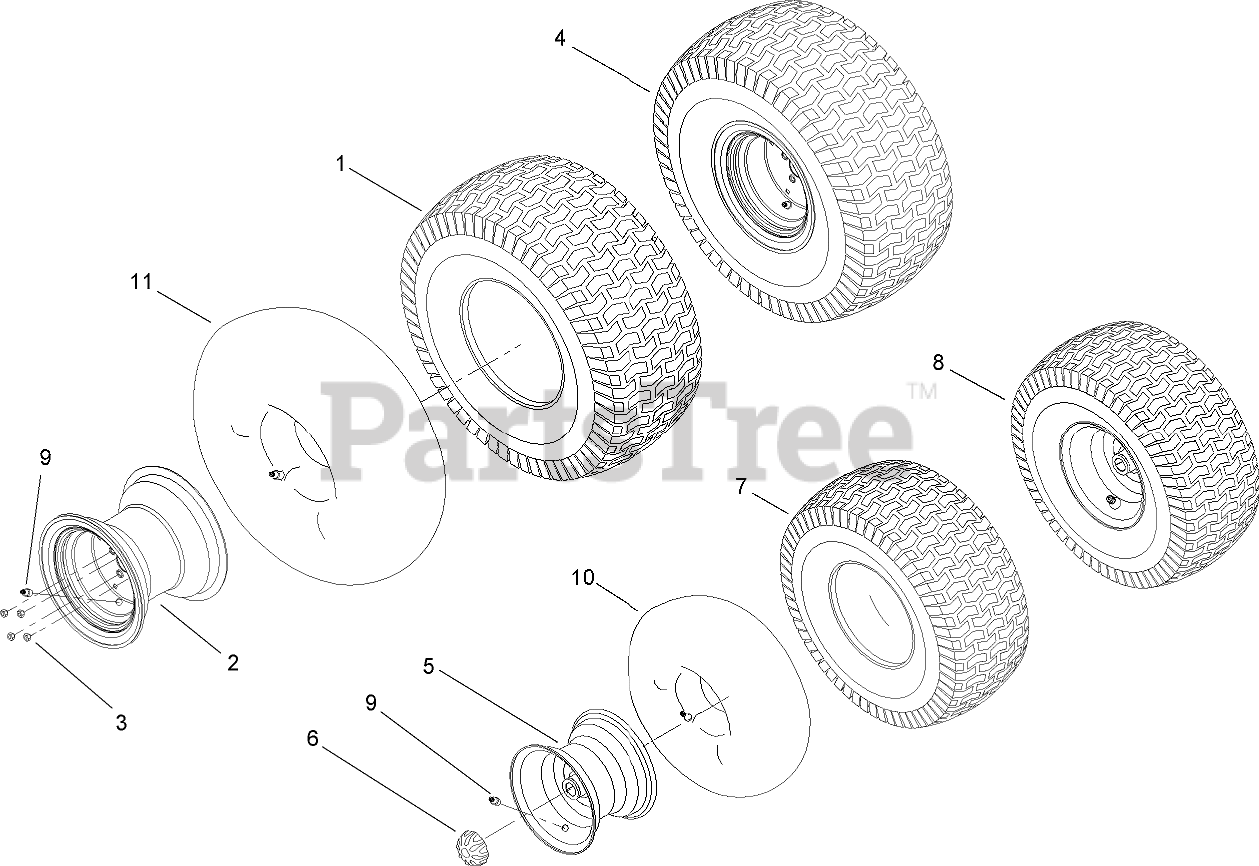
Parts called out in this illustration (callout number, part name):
1	TIRE-TURF
2	RIM ASM
3	NUT-LUG
4	WHEEL ASM
5	RIM ASM
6	CAP-HUB
7	TIRE-TURF
8	WHEEL ASM
9	VALVE-AIR, TUBELESS
10	TUBE-INNER
11	TUBE-INNER
